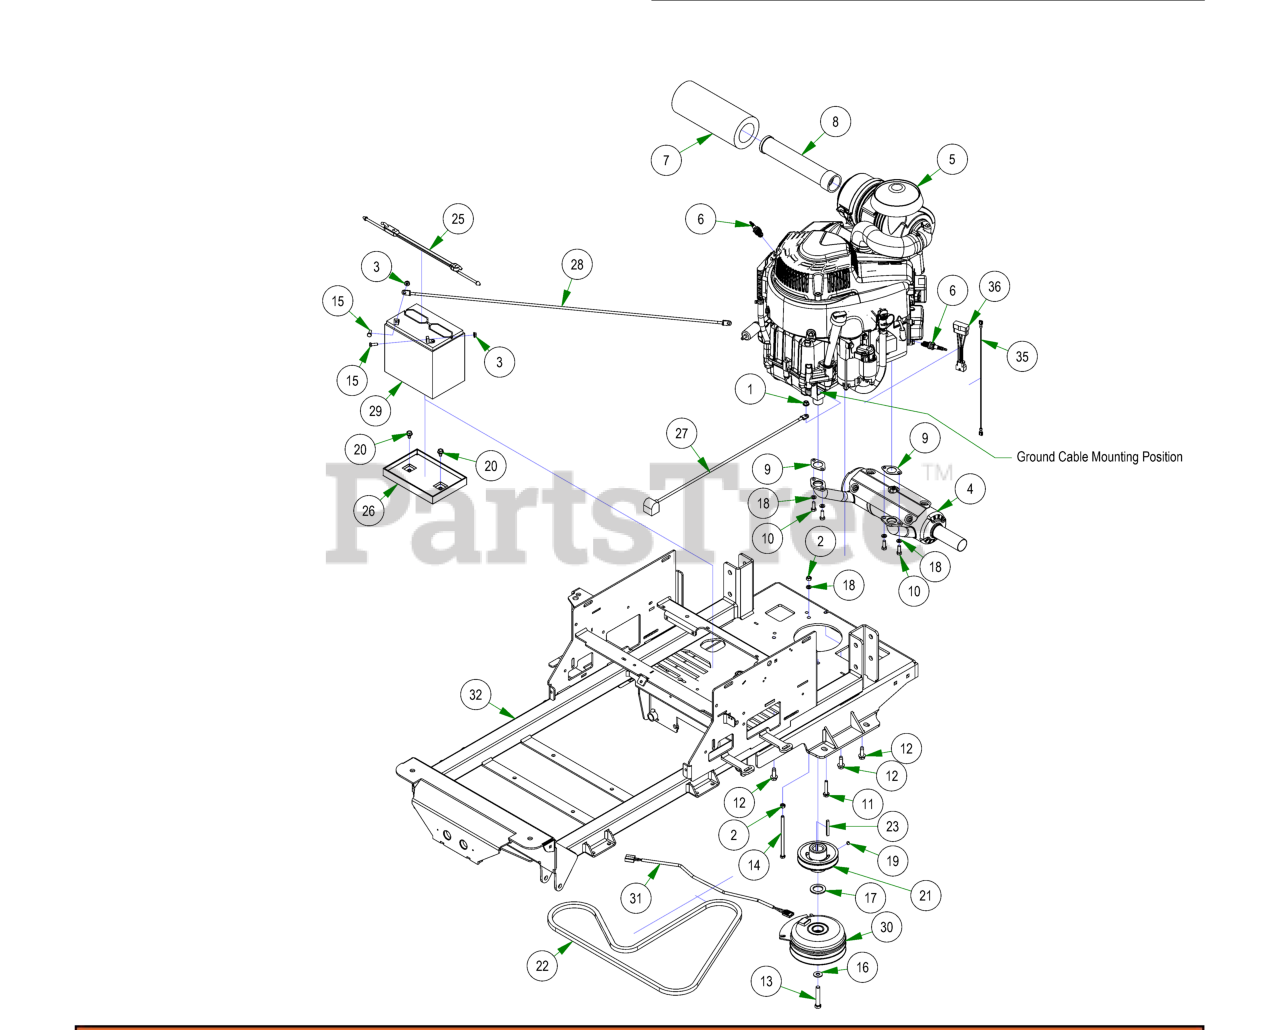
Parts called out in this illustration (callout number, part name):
1	5/16-18 Gr5 Distorted-Thread Flange Locknut
2	5/16-18 HEX NUT ZINC
3	1/4-20 HEX SERRATED FLANGE NUT HARD/ZINC
4	Maverick HD 28 EFI Muffler
5	28HP Briggs Vanguard 810cc
6	Spark Plug
7	Canister Air Filter- Outer
8	Canister Air Filter- Inner
9	Exhaust Gasket
10	Torx Bolt-Exhaust
11	5/16-18x1-3/4 Gr5 Hex Flange Screw Zinc Clear
12	3/8-16 X 1-1/8 HEX WASHER UNSLOT SERRATED (TRI-LOB) TRS ZINC YELLOW
13	7/16-20 X 2-1/2 HEX Bolt GR 8 W/ Patch
14	5/16-18 X 5-1/2 HEX CAP SCREW (GR.5) ZINC
15	1/4-20 X 3/4 HEX CAP SCREW (GR.5) ZINC
16	3/8 FLAT WASHER USS (1" OD) ZINC
17	1.140 ID X 1.750 OD X .132 THICK FLAT WASHER PLAIN
18	5/16 SPLIT LOCKWASHER ZINC
19	5/16-24 X 1/4 SOCKET SET SCREW (CUP PT) PLAIN
20	5/16-18 X 1/2 HWH unslot (F) tcs zinc
21	4 3/4 Motor Pulley
22	75.8" Pump Belt
23	1/4 X 2 SQ MACHINERY KEY 1018 STL PLAIN
24	2023 Battery Hold Down Assembly
25	2023 Rubber Battery Hold Down Strap
26	Battery Tray
27	24 inch Black Cable – MZ/ZT
28	36" Red Battery Cable
29	SP-35 Battery
30	Clutch Assembly
31	Clutch Pigtail
32	2023 Maverick Frame - Painted
33	1 Quart of 10W30 Oil
34	Unleaded Gasoline
35	Compact Outlaw/Honda Starter Jumper Wire
36	2021 28 Briggs EFI Pigtail
37	12 Black Plastic Tie
